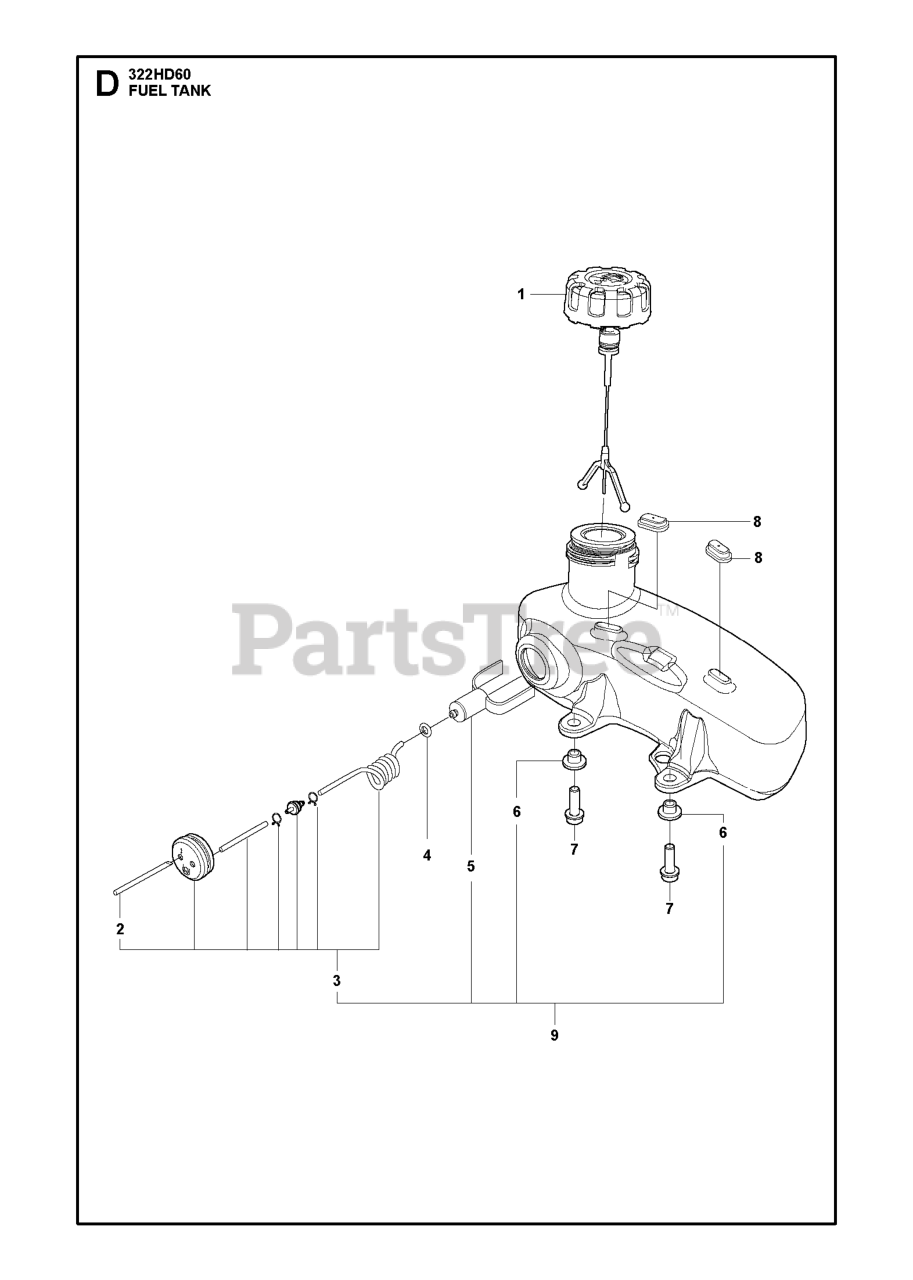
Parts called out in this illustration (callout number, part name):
5	FUEL FILTER
6	RIVET TUBULAR
8	FUEL TANK ISOLATOR
9	FUEL TANK ASSY
